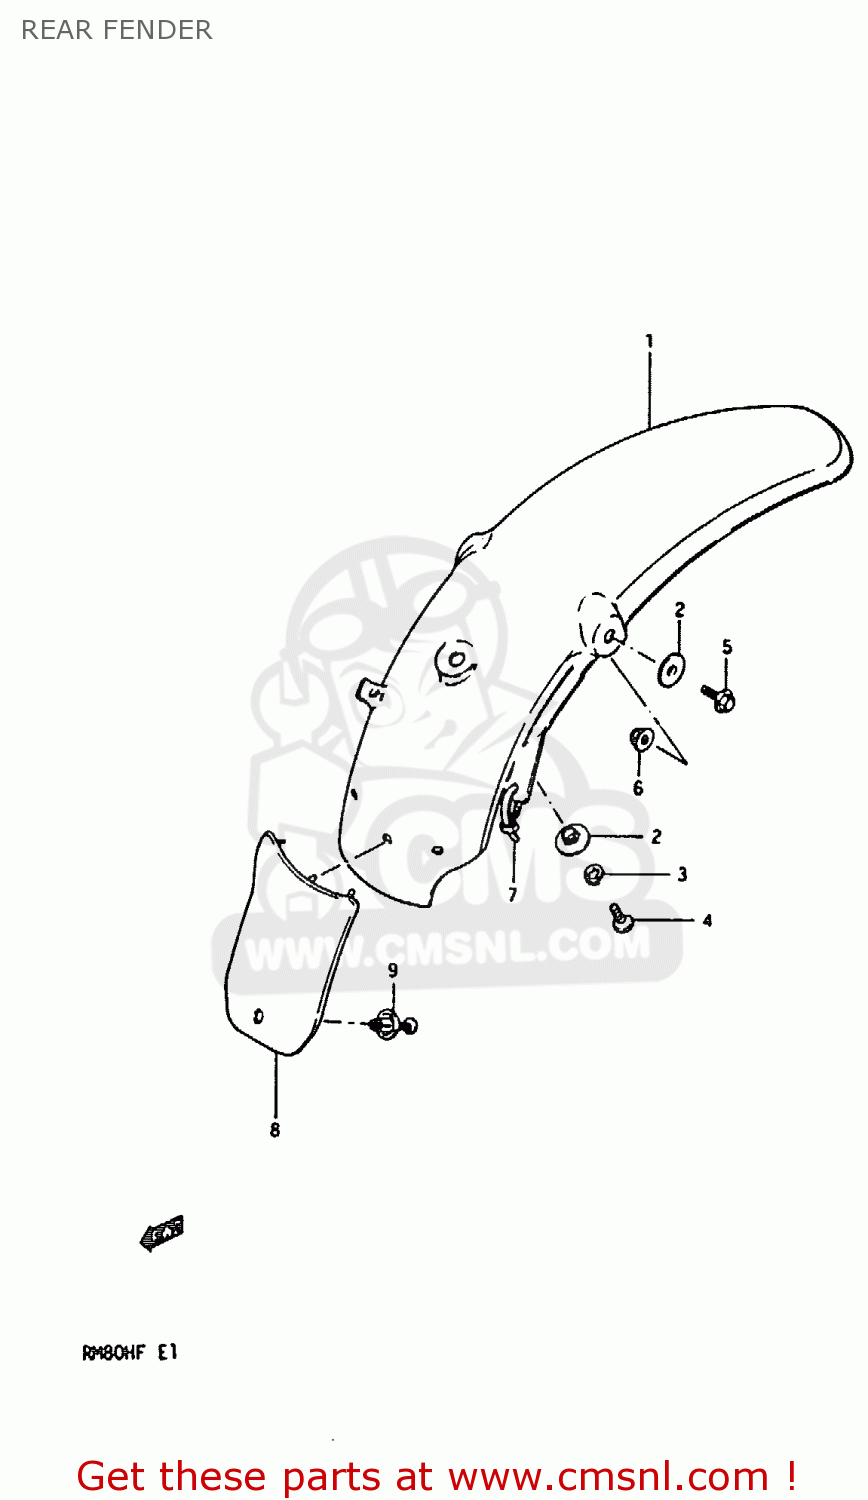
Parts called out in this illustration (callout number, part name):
1	FENDER, REAR (YELLOW)
2	WASHER
3	LOCK WASHER
4	BOLT, UPPER
5	BOLT,REAR
6	NUT
7	CLAMP
8	GUARD,MUD
9	CLIP
